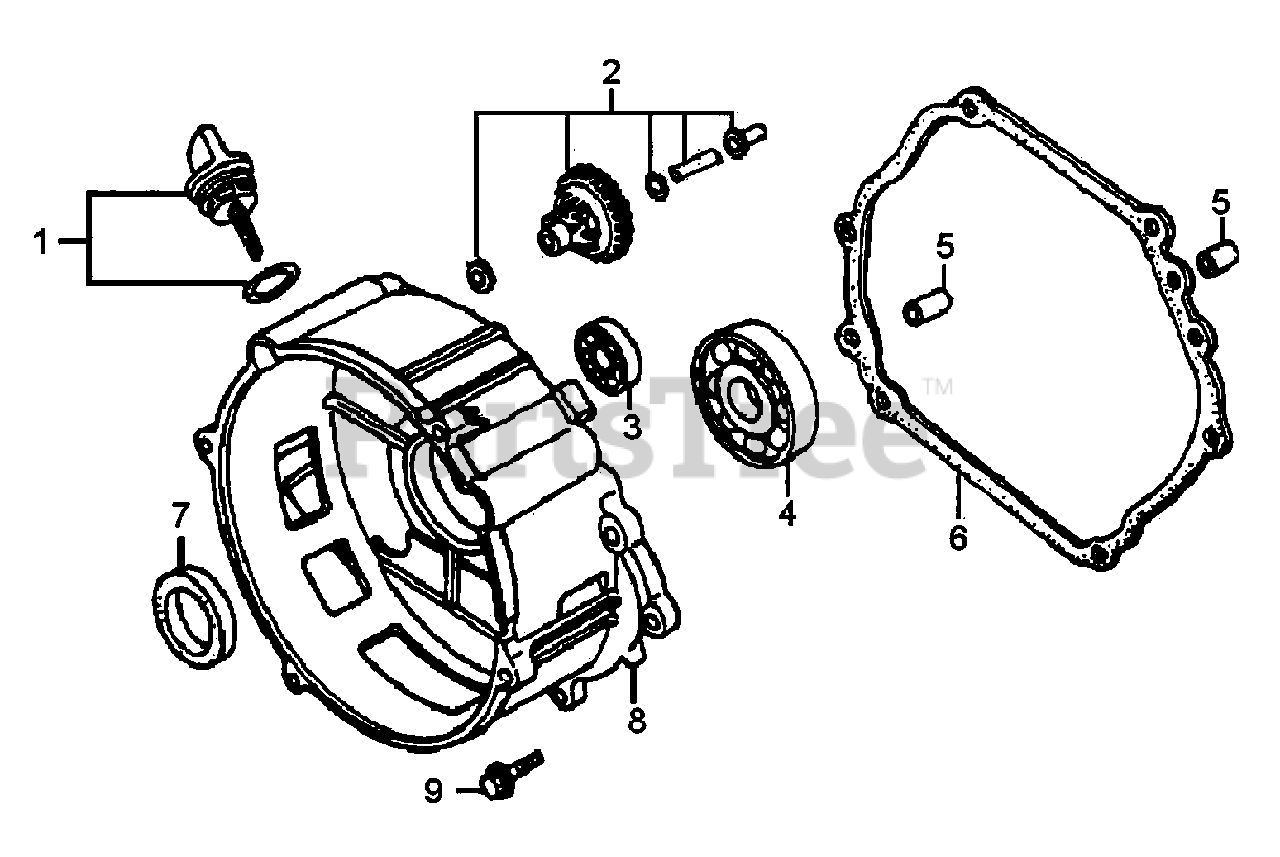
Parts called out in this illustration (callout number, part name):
1	CAP COMP., OIL FILLER
2	GOVERNOR ASSY.
3	BEARING, RADIAL BALL 6202
4	BEARING, RADIAL BALL 6207
5	PIN, DOWEL 8X12
6	PACKING, CASE COVER
7	OIL SEAL 35X52X7
8	CRANKCASE COVER
9	BOLT, FLANGE M8X40
